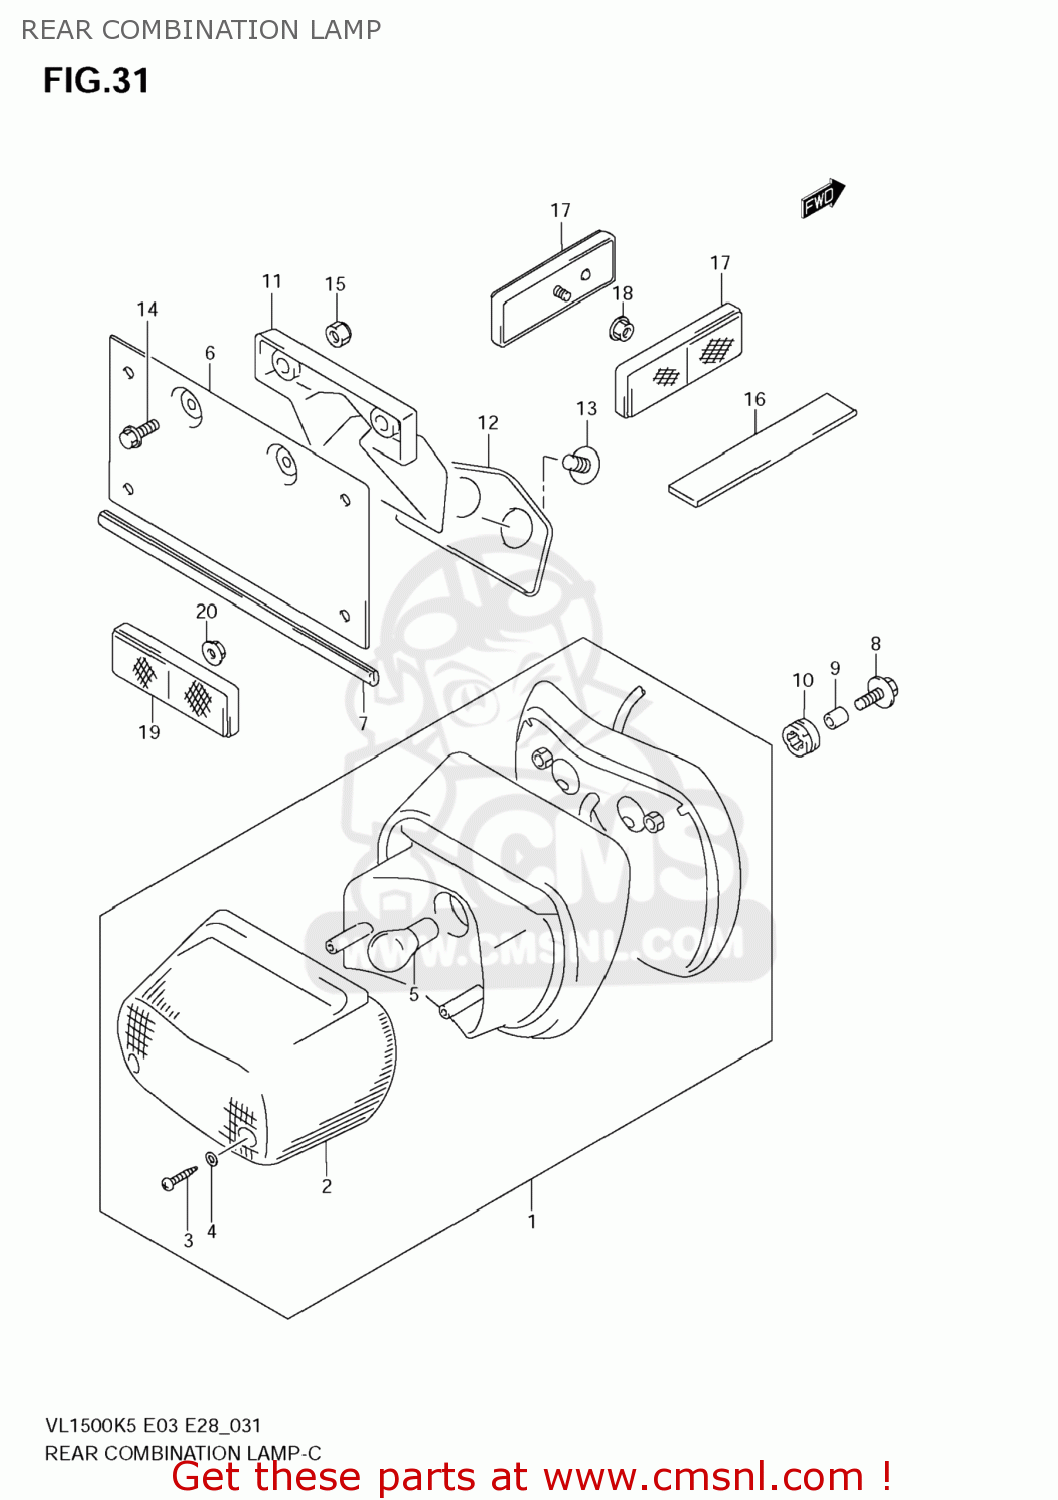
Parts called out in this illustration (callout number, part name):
1	LAMP ASSY,RR COMBINATION
2	LENS
3	SCREW
4	GASKET (NAS)
5	BULB(12V21/5W)
6	HOLDER,LICENSE PLATE
7	MOLDING
8	BOLT(6X20)
9	SPACER(6.5X10X12)
10	CUSHION
11	STAY,LICENSE PLATE HOLDER
12	CUSHION,LICENSE PLATE HOLDER
13	BOLT(6X16)
14	SCREW(6X16)
15	NUT
16	PROTECTOR(20X90)X1.0
17	REFLEX REFLECTOR ASSY,RR
18	NUT
19	REFLECTOR ASSY,RR
20	NUT
